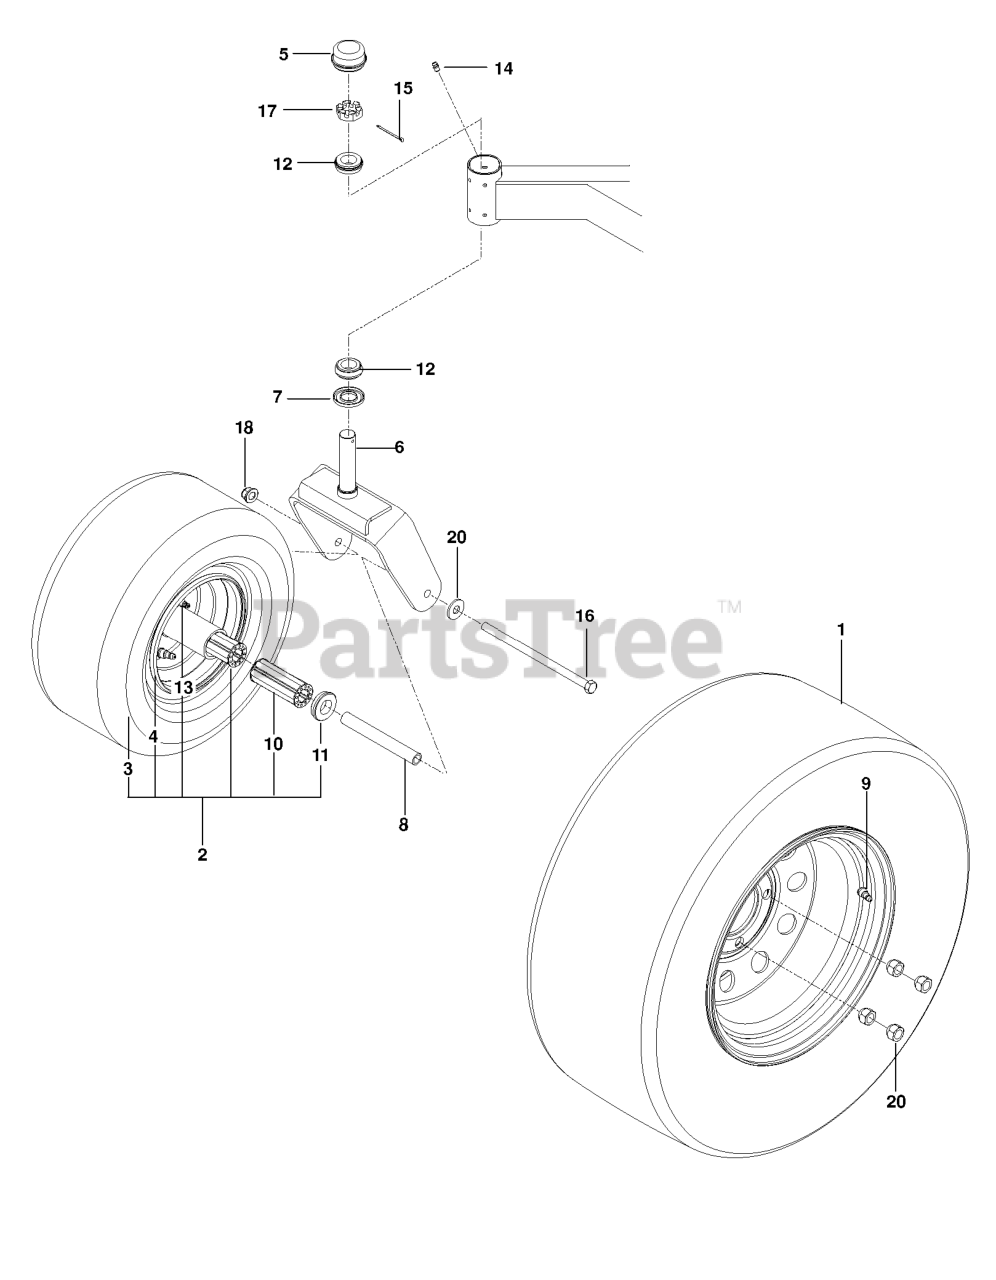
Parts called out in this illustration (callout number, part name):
1	RP WHEEL.ASM.23X10.5-12.TURFMA
2	TIRE.ASSEM.CASTER.13X6.5-6.SIL
3	TIRE.13X6.50-6.4.PLY
4	WHEEL.6X4.50.CASTER.SILVER
5	GREASE CAP
6	YOKE.CASTER.ORANGE
8	SPACER, PIVOT
9	VALVE STEM TR-412
10	ROLLER BEARING-CAGED 3 1/4'
11	BEARING RETAINER
12	TAPERED ROLLER BRG
13	ZERK
15	COTTER PIN 1/8 X 2
16	HEX SCREW 1/2-13 X 9.5 GR5
17	NUT 1"C HEX SLOTTED
18	NUT, 1/2-13 HEX FLG NYLOC ZD
19	LUG NUT 1/2F
20	WASH USS FLAT 1/2
